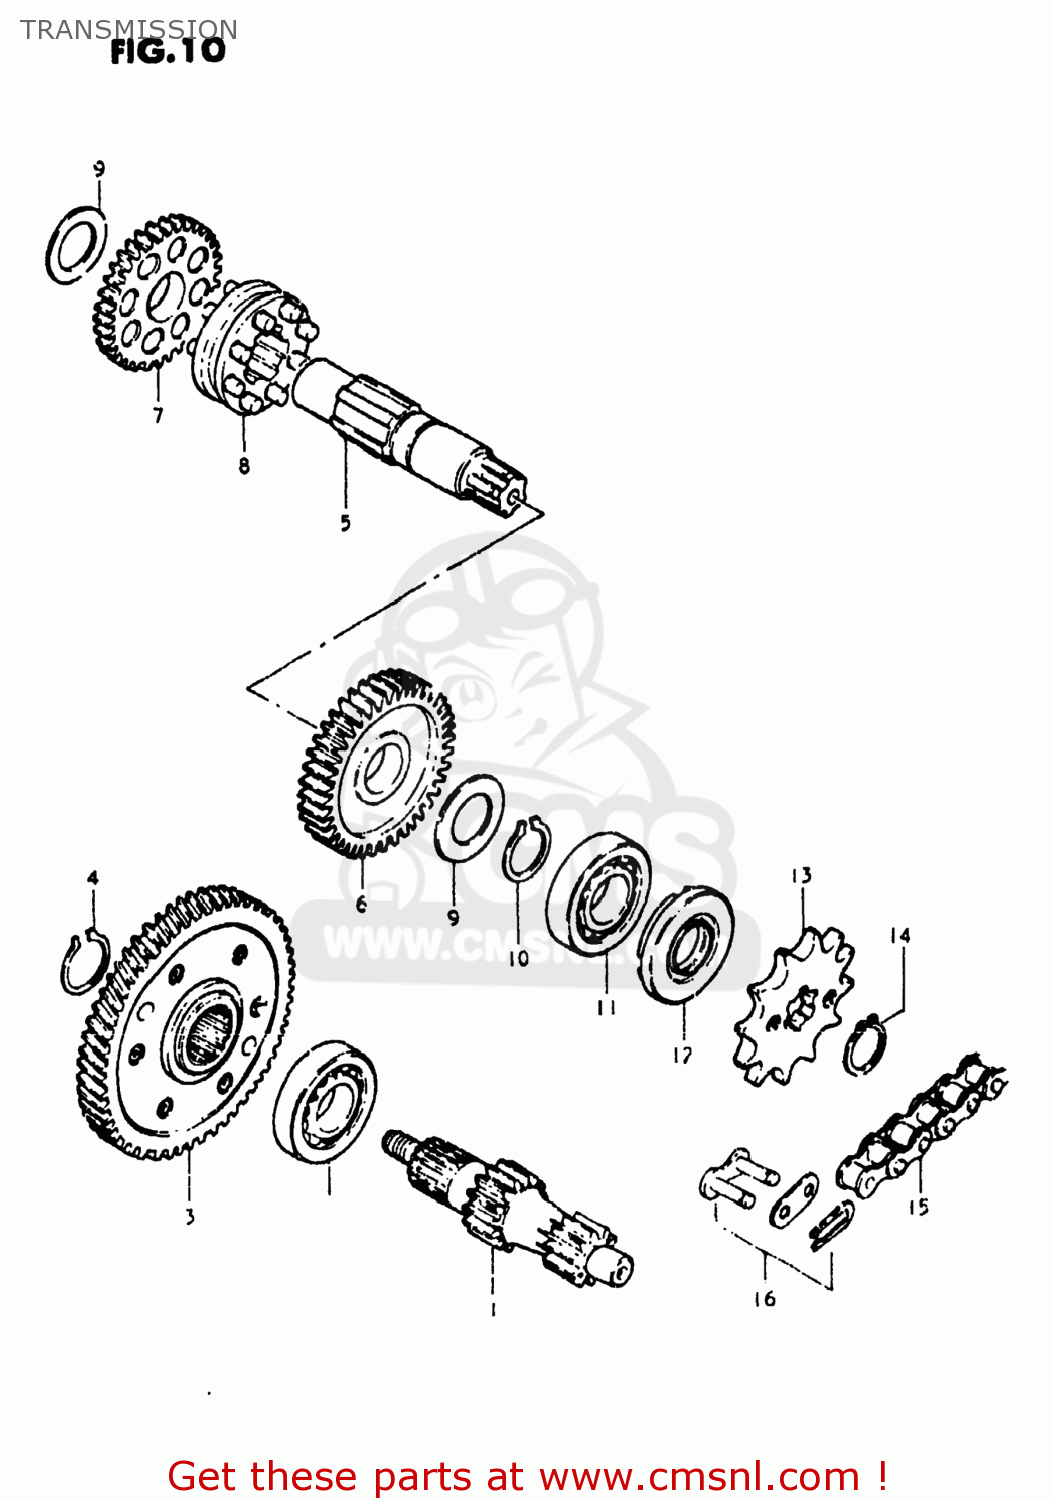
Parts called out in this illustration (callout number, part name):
1	SHAFT,COUNTER
2	BEARING
3	GEAR ASSEMBLY,PRIMARY DRIVE
4	CIRCLIP
5	SHAFT,DRIVE
6	GEAR,FIRST DRIVEN
7	GEAR,SECOND DRIVEN
8	WHEEL,FIRST GEAR
9	WASHER,THRUST
10	CIRCLIP
11	BEARING
12	SEAL,OIL(17X29X7)
13	SPROCKET,ENGINE
14	CIRCLIP,16MM
15	CHAIN ASSEMBLY,DRIVE
16	JOINT ASSEMBLY,CHAIN
